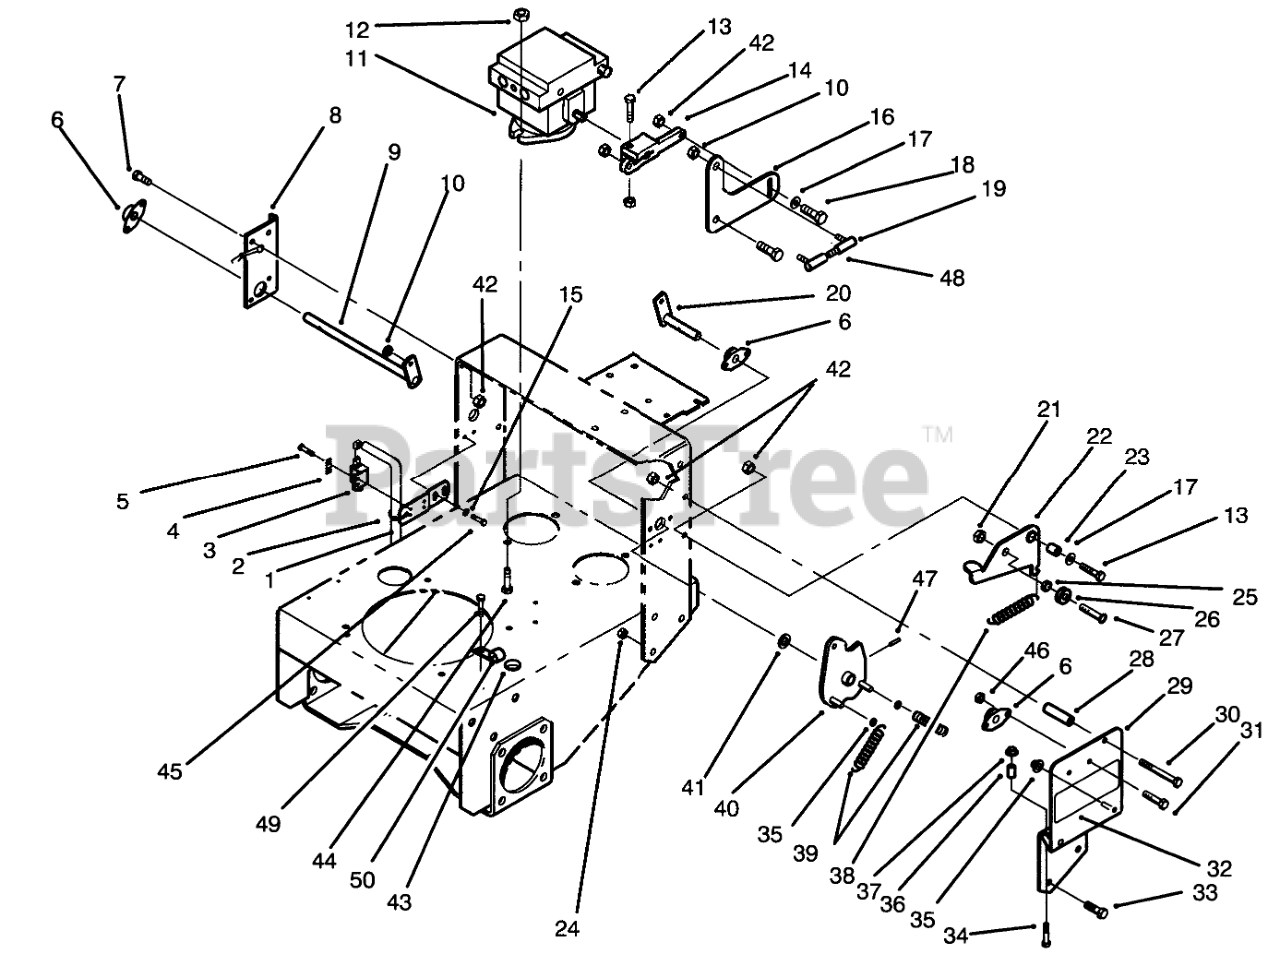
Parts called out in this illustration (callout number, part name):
1	NEUTRAL BRACKET B
2	TIE-CABLE
3	SWITCH-POLE, SINGLE
4	PLATE-SWITCH
5	SCREW-TAPTITE
6	SIDE FLANGE BEARING ASM
7	SCREW-HH
8	Bracket-Bushing
9	RH LEVER WA
10	NUT-LOCK, NI
11	HYDRAULIC PUMP
12	NUT-HF
13	SCREW-HH
14	ARM-PUMP
15	WASHER-FLAT
16	FOLLOWER ARM B
17	WASHER-PLAIN
18	SCREW-HH
19	JOINT-BALL
20	LH LEVER WA
21	NUT-LOCK, NI
22	Detent Arm Assembly L.H.
23	BUSHING-ARM, DETENT
24	NUT-LOCK, NI
25	SPACER-BEARING
26	BEARING-BALL
27	SCREW-HSBH
28	STOP-REVERSE
29	LEFT BRACKET WA R
30	SCREW-HH
31	SCREW-HH
32	DECAL-HYDRO
33	SCREW-HH
34	SCREW-HH
35	NUT-PUSH
36	SPACER-TUBULAR
37	NUT-LOCK, HHF
38	SPRING-DETENT
39	SPRING-EXTENSION
40	LH PIVOT ARM WA RO
41	WASHER-THRUST
42	NUT-LOCK, NI
43	GROMMET
44	SCREW-HH
45	Screw
46	NUT-LOCK, NI
47	PIN-ROLL, SLOTTED
48	BALL JOINT ROD
49	SCREW-HWH
50	CLAMP-R
51	NUT-PUSH IN
52	STOP BRACKET
